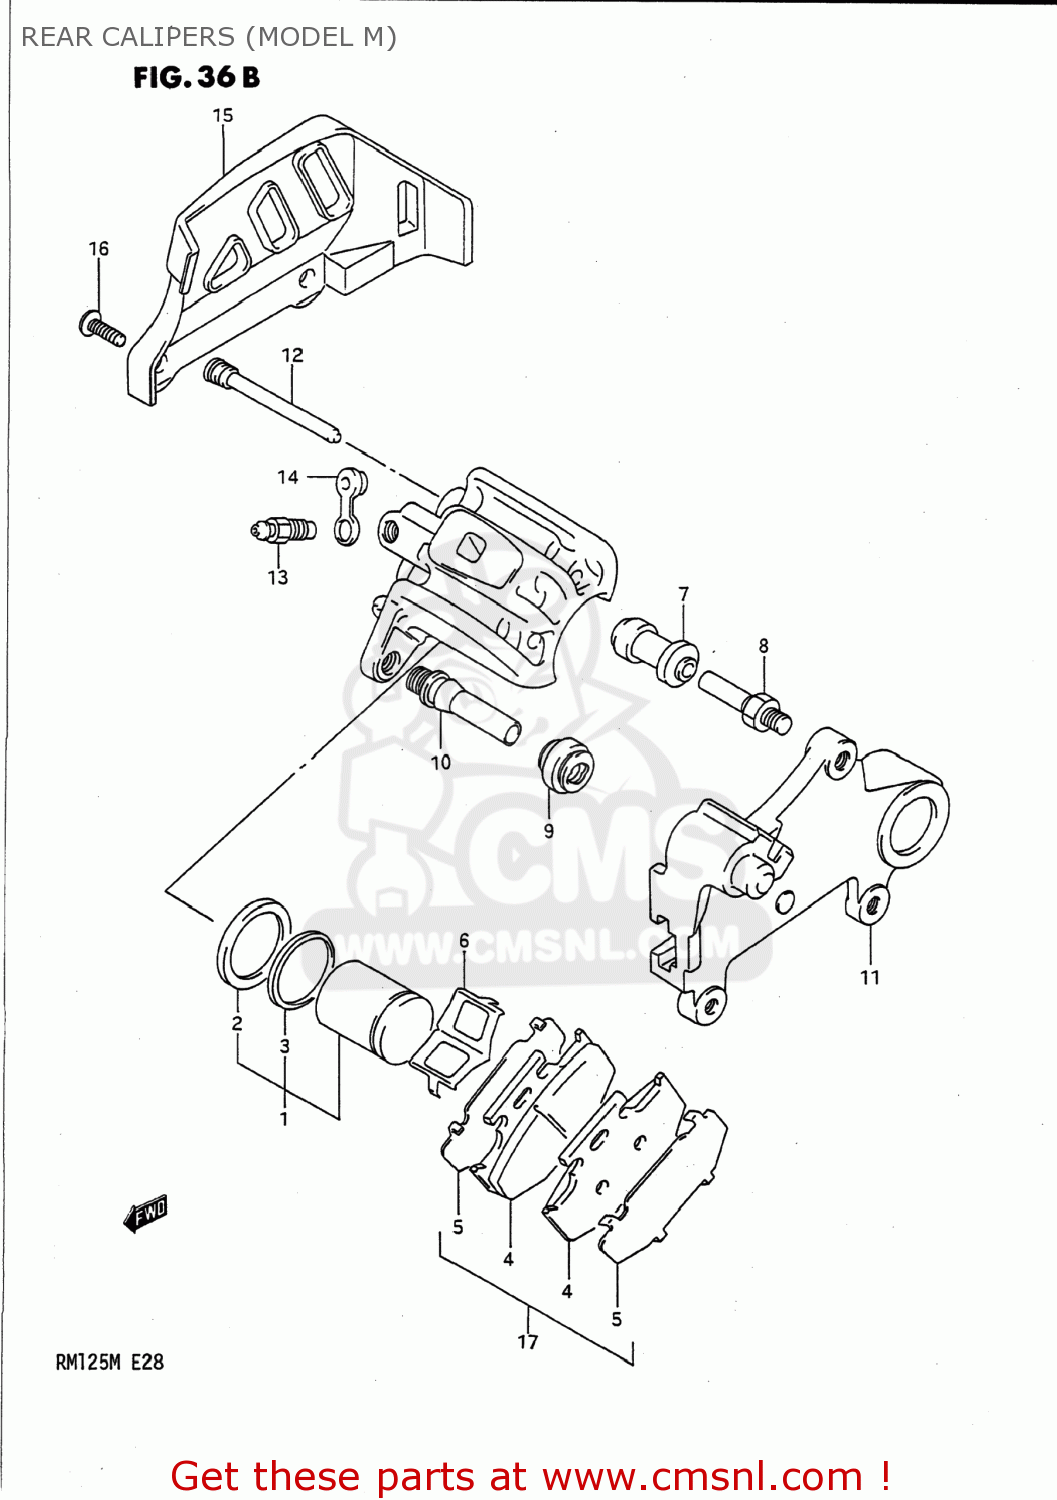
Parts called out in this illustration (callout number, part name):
1	PISTON SET
2	SEAL,PISTON
3	SEAL,DUST
4	PAD
5	SHIM
6	SPRING,PAD
7	BOOT
8	PIN,BOLT
9	BOOT
10	PIN
11	BRACKET
12	PIN,HANGER
13	BLEEDER
14	CAP,BLEEDER
15	GUARD,RR CALIPER
16	SCREW(6X12)
17	PAD SET,RR CALIPER(STRONG)
